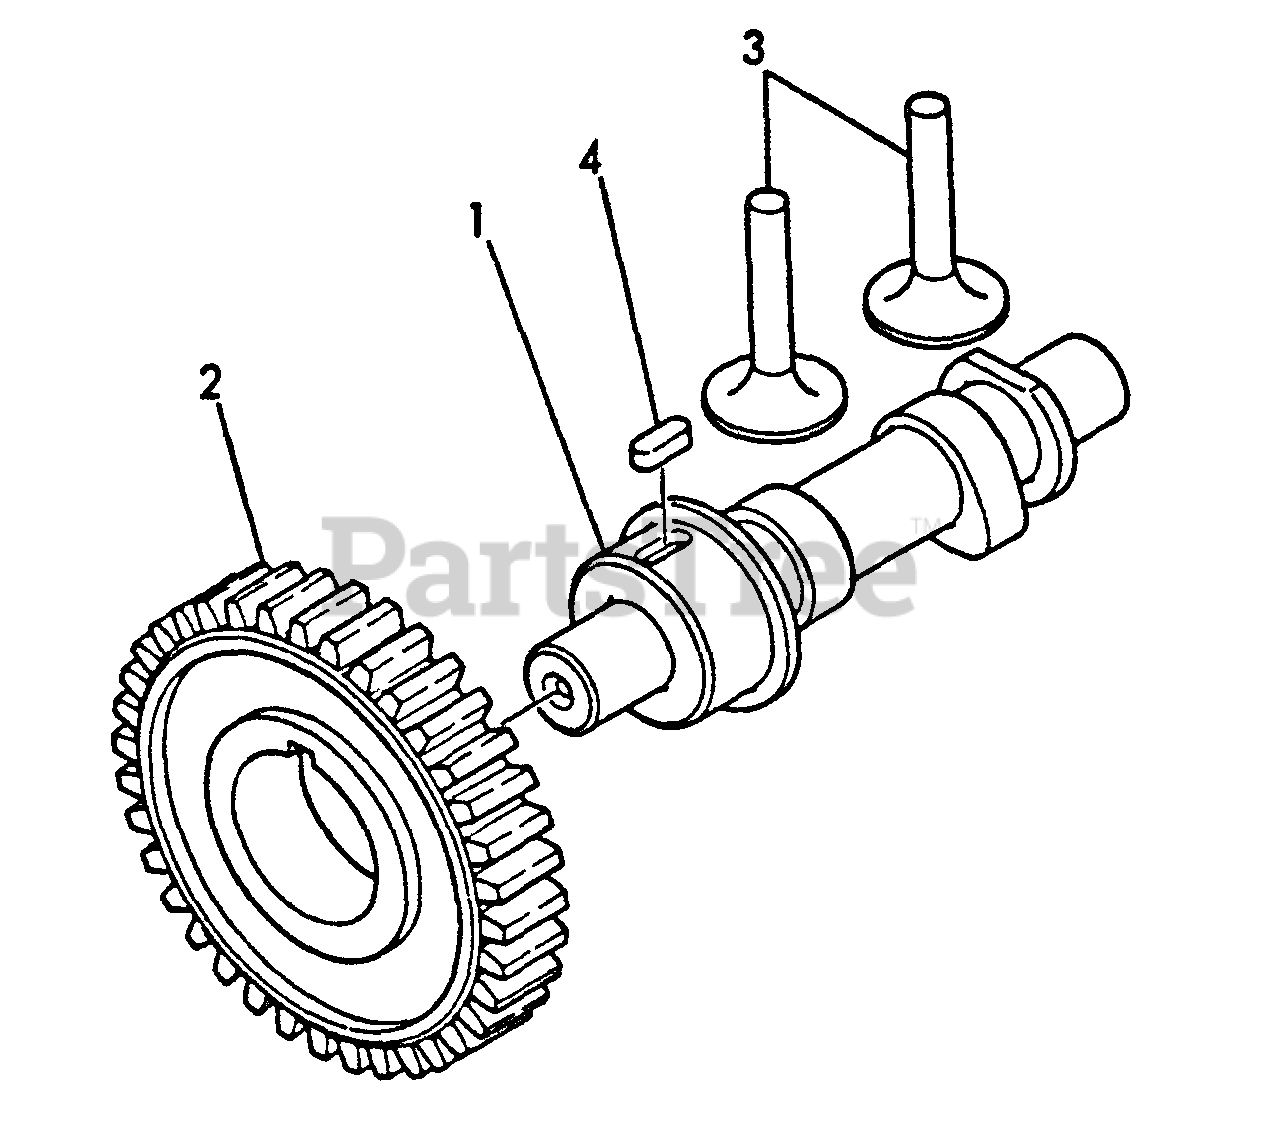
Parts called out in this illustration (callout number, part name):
1	CAMSHAFT
2	GEAR, CAMSHAFT
3	TAPPET
4	KEY - 4×10
